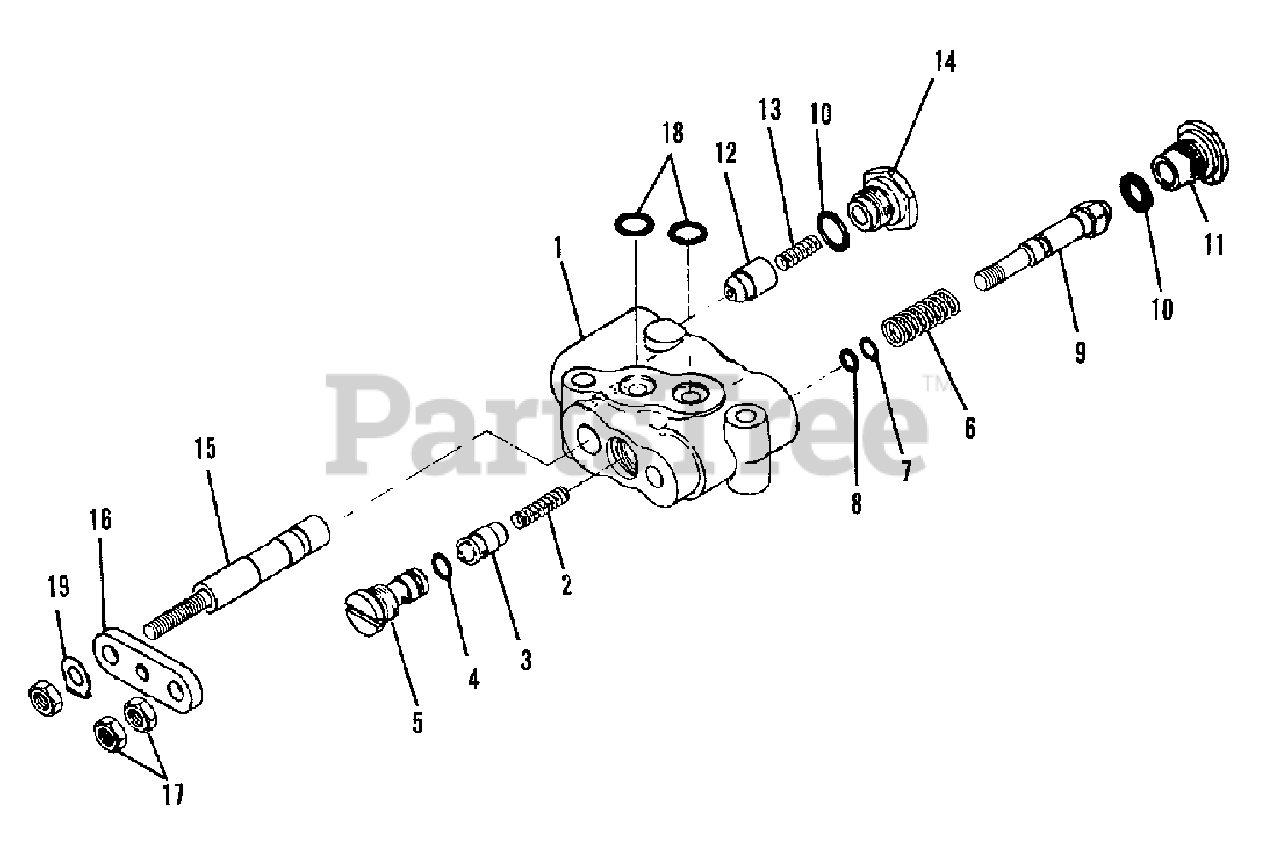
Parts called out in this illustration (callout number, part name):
1	BODY ASSEMBLY (Incl. SPOOL)
3	PLUG, spring
8	RING, back-up
11	SEAT, poppet
12	PLUG, spring
13	SPRING, small
14	SEAT, spring
15	SPOOL (Not serviced; order 2098384 BODY ASSEMBLY)
16	PLATE, spool
18	O-RING, body ASSEMBLY
19	LOCK, plate
